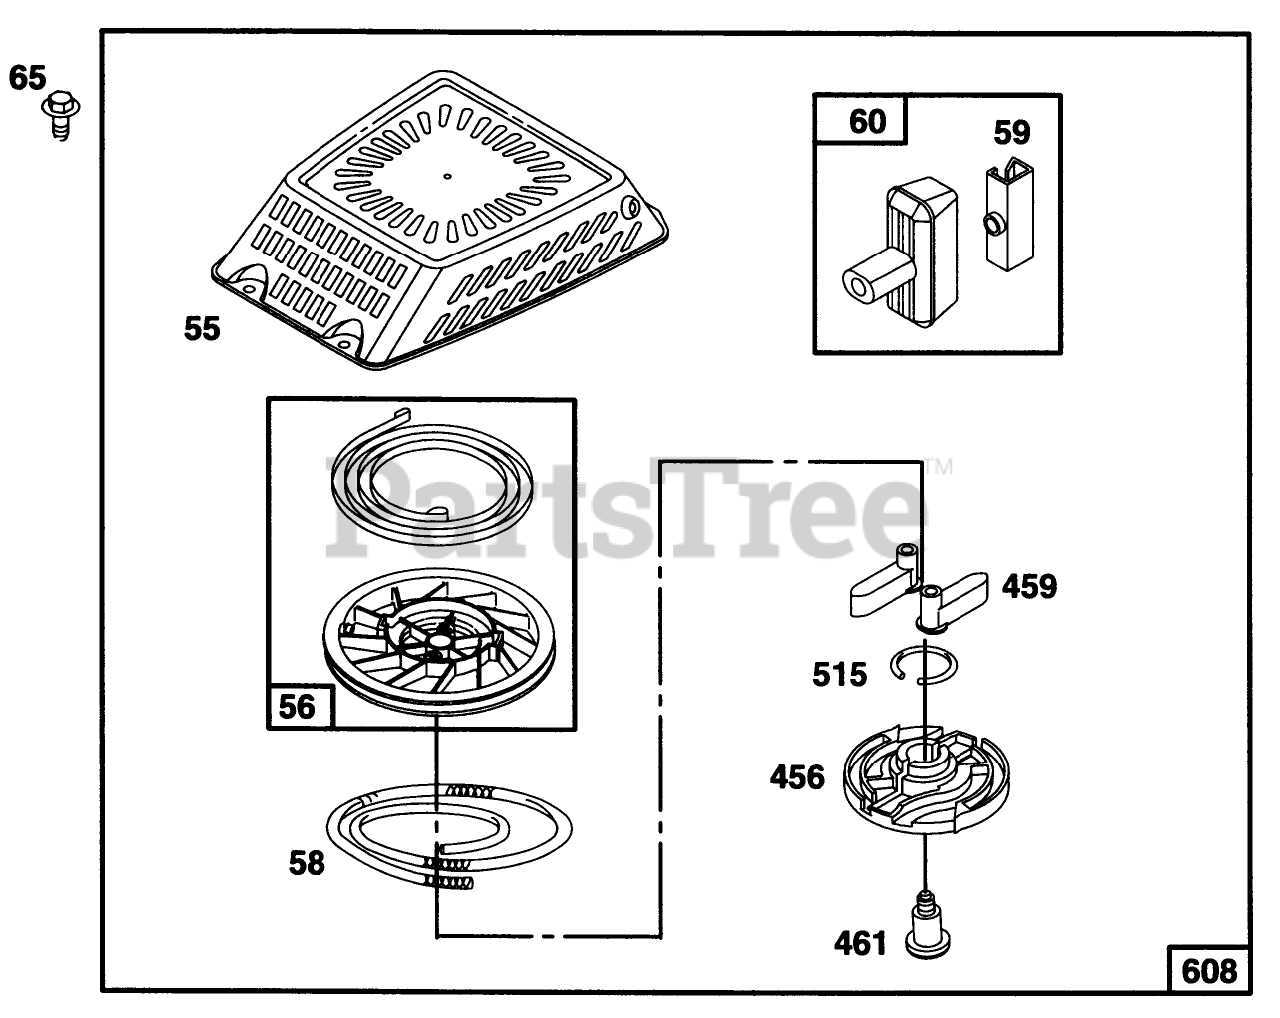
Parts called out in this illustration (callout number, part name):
56	PULLEY-STARTER, REWIND
58	ROPE-STARTER
59	INSERT-HANDLE, REWIND
456	RETAINER-STARTER, REWIND
459	PAWL-STARTER
515	SPRING-TORSION
